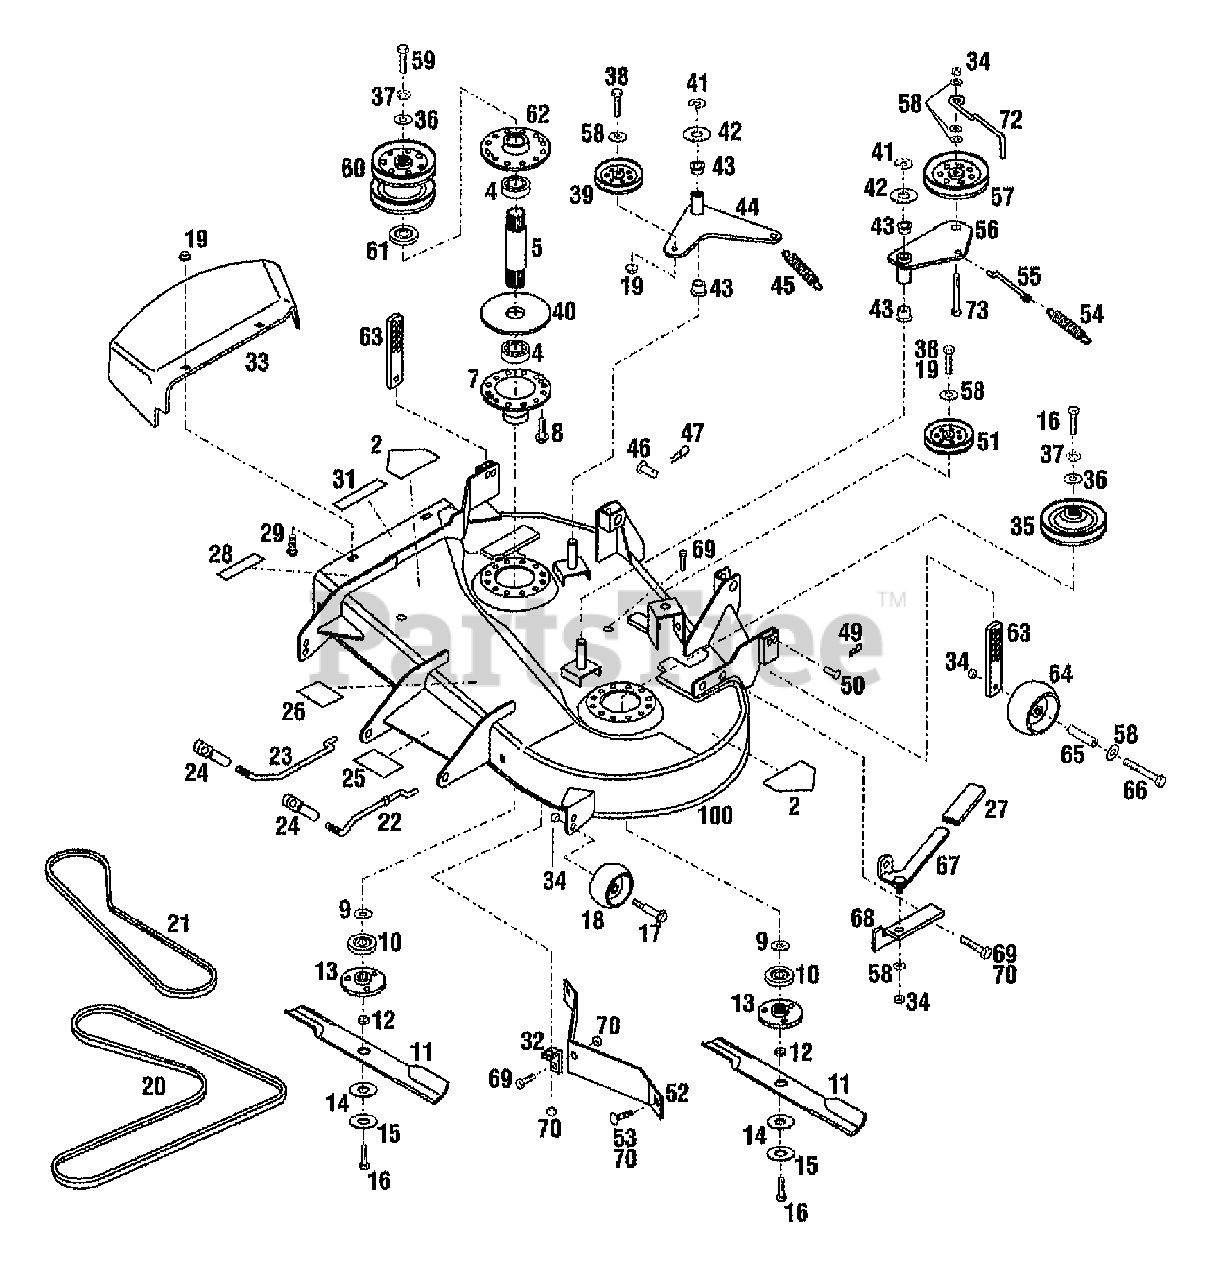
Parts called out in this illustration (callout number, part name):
2	DECAL-OPEI CAUTION
4	BEARING-BALL
5	SHAFT-ARBOR
7	HOUSING-ARBOR BOTTOM
8	SCR-HFLK 5/16-18X.625 STH
9	WASHER-SHIM
10	SHIELD-GRASS
11	BLADE-MOWER
12	COLLAR-ARBOR
13	ADAPTER-BLADE
14	WASHER-SPLINED
15	WASHER-LK CONICAL .49 ID
16	SCR-HH 1/2-14X1.00
17	SCR-SHLDR 3/8-16
18	WHEEL-GAGE
19	NUT-HFLK 3/8-16 ZP
20	BELT-V
21	BELT-V
22	ROD-LIFT FRONT LH
23	ROD-LIFT FRONT RH
25	DECAL-LIFT ROD
26	DECAL-BELT DRIVE
28	DECAL-CUTTING LINE
29	SCR-CARR 3/8-16X.75 G5 ZP
31	DECAL-DANGER
32	BRACKET-MOWER
33	DEFLECTOR-MOWER
34	NUT-LOCK 3/8-16
35	ASSM-SHEAVE
36	WASHER-1.37X.453X.179 ZP
37	WASHER-LK .438 ZP
38	SCR-HH 3/8-16X1.5 G5 ZP
39	PULLEY
40	GASKET-FOAM
41	RING-RETAINING
42	WASHER-1.305X.649X.098 ZP
43	BEARING-FLANGE
44	ASSM-IDLER ARM
45	SPRING-EXTENSION
46	PIN-CLEVIS .625X2.25
47	PIN-HITCH .125X2.56 ZP
49	CLIP-HAIRPIN .07 DIA
50	PIN-CLEVIS .375 X .937 ZP
51	IDLER 4" B-GROOVE
53	SCR-CARR 5/16-18X.75
54	SPRING
55	ROD-IDLER
56	ASSM-IDLER ARM
58	WASHER-.986X.437X.083 ZP
59	SCR-HHC 7/16-14X2 1/4
60	ASSM-SHEAVE
61	BEARING-UPPER SHIELD
62	HOUSING-ARBOR TOP
63	LEVER-GAGE WHEEL ADJUST
64	WHEEL-GAGE
65	SPACER-GAGE WHEEL
66	SCR-HH 3/8-16X3.5 G5 ZP
67	ASSM-LEVER ENGAGEMENT
68	BRACKET-LEVER
69	SCR-HHC 5/16-18X.75 GR 5 ZP
70	NUT-TOP/LK 5/16-18 ZP
72	GUIDE-BELT
73	SCR-HH 3/8-16X2.25 G5 ZP
100	BASE-MOWER 36" W/DECALS
